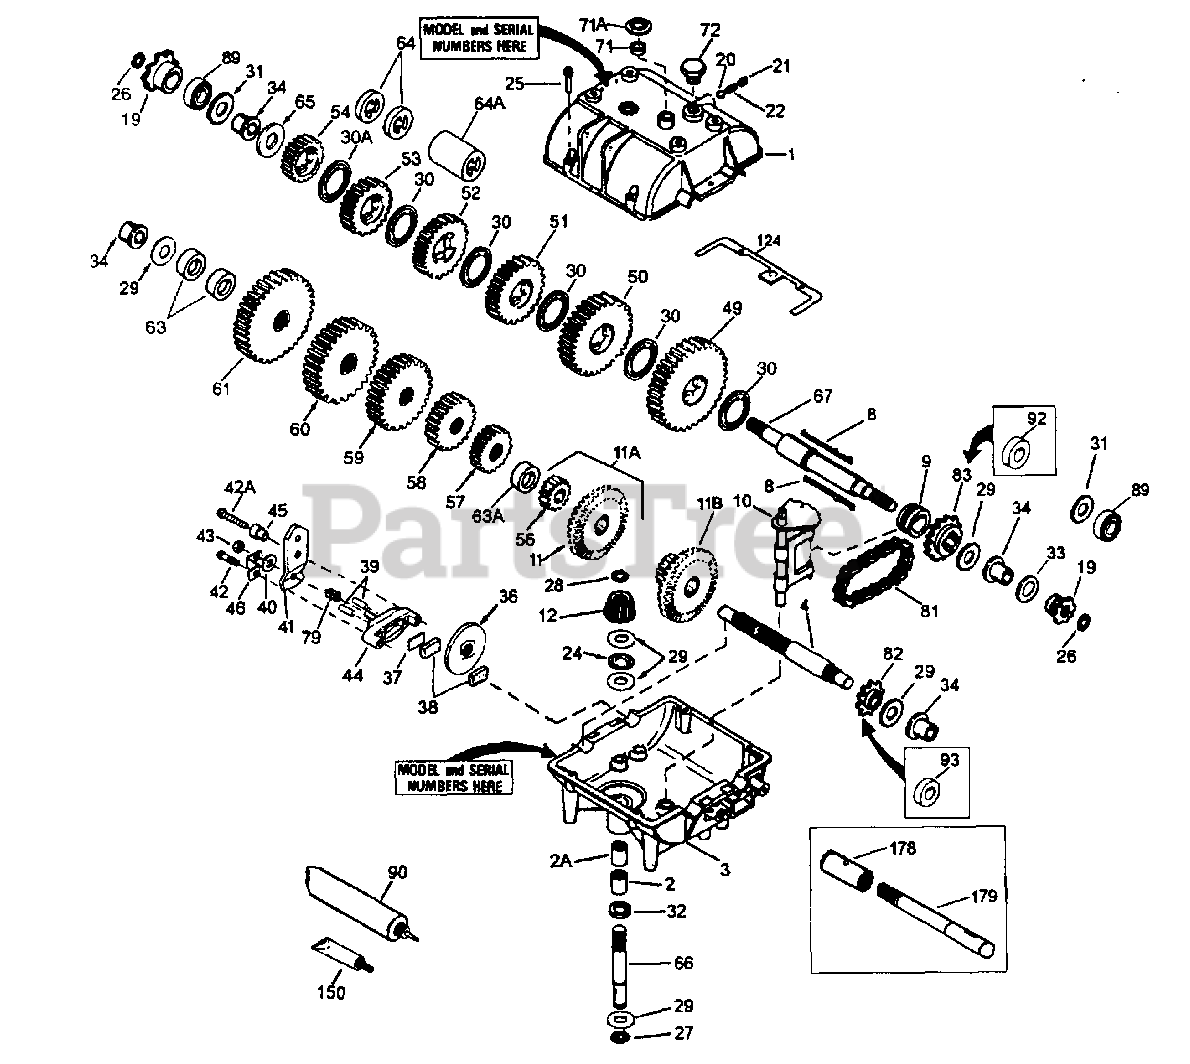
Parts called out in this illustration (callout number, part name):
1	Case, Transmisson
2	Needle Bearing Grease Spec
2A	Needle Bearing
3	Case, Transmission
8	Shift Key
9	Shift Collar
10	Shift Rod & Fork
11	Bevel Gear
12	Bevel Pinion
20	Steel Ball, 5/16" dia.
21	Set Screw, 3/8-16 x 3/8"
22	Spring
24	Thrust Bearing
25	Screw, 1/4-20 x 1-1/4" (6)
27	Retaining Ring
28	Retaining Ring
29	Washer (6)
30	Washer (5)
32	O Ring
34	Flanged Bushing
49	Spur Gear
50	Spur Rear
51	Spur Gear
52	Spur Gear
53	Spur Gear
56	Spur Gear
57	Spur Gear
58	Spur Gear
59	Spur Gear
60	Spur Gear
65	Washer
66	Input Shaft (3-11/16" long)
67	Shifter & Brake Shaft
71	Square Cut Ring
72	Threaded Plug
81	Roller Chain
82	Sprocket
83	Sprocket
90	Grease
150	Gasket Eliminator
178	Coupling
179	Connector Shaft
